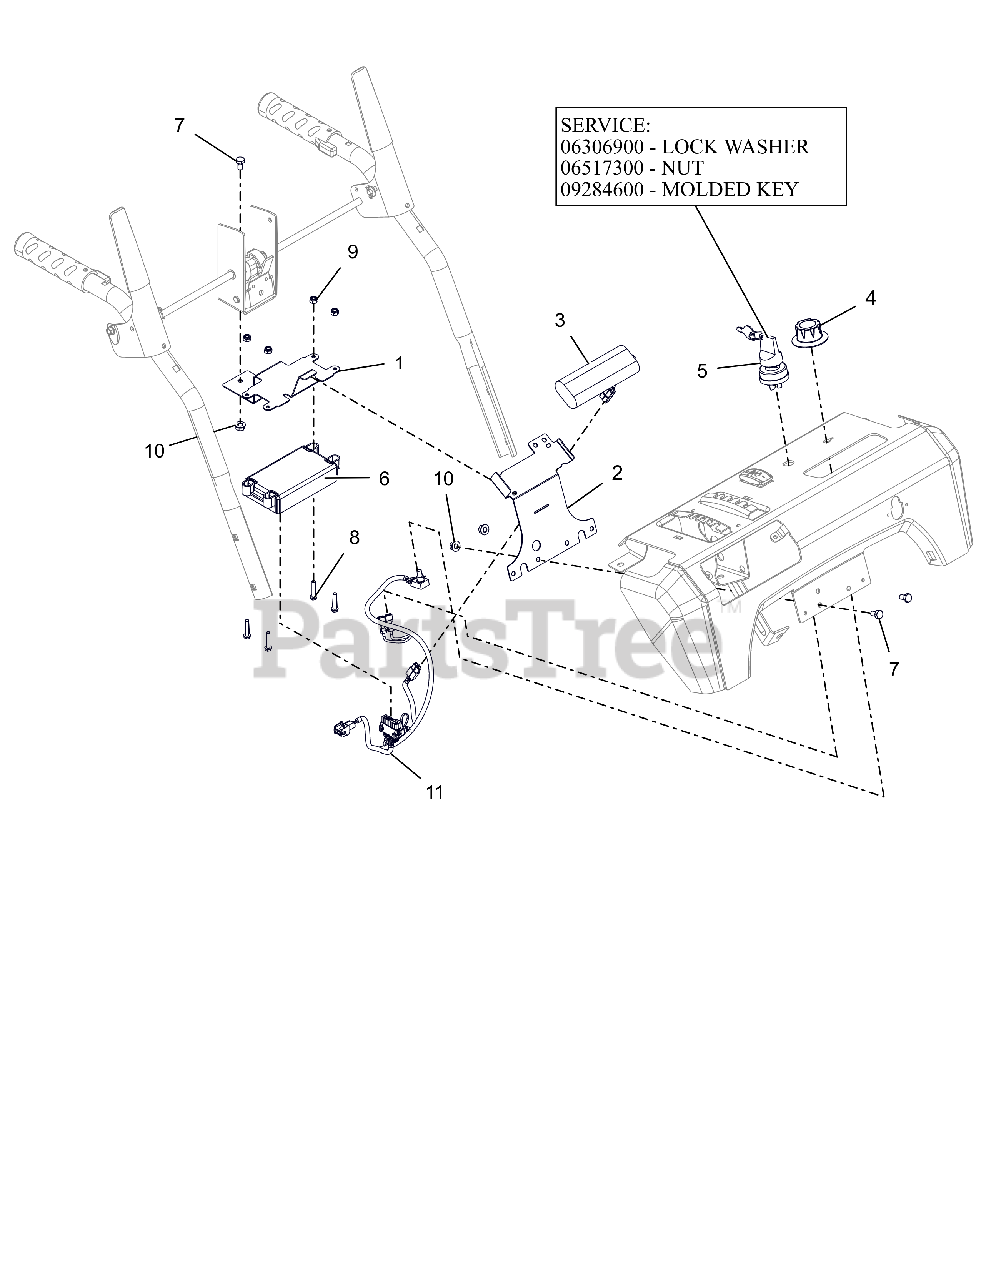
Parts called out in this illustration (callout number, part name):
1	BRACKET, ENGINE EFI-LCT LOWER
2	BRACKET, ENGINE EFI-LCT UPPER
3	BATTERY, SNOW EFI - 7.2V
4	KNOB, CONTROL - 2.063 ID
5	IGNITION SWITCH ASM - 2 POS
5	WSHR-LK-INT .625X.045 YWZC
5	NUT-PANEL .625-32 GRECO
5	KEY W/ SHIELD
6	ECU, AX369 EFI
7	@BLT-HEX .25-20X.50 GR5 YWZC
8	@SCR-MCH 10-24X1.00 HWH YWZC
9	@NUT-LK-NYL 10-24 W/INSRT YWZC
10	@NUT-LK-TOP-FLG .25-20 YWZC
11	HARNESS,WIRE - EFI ECU
